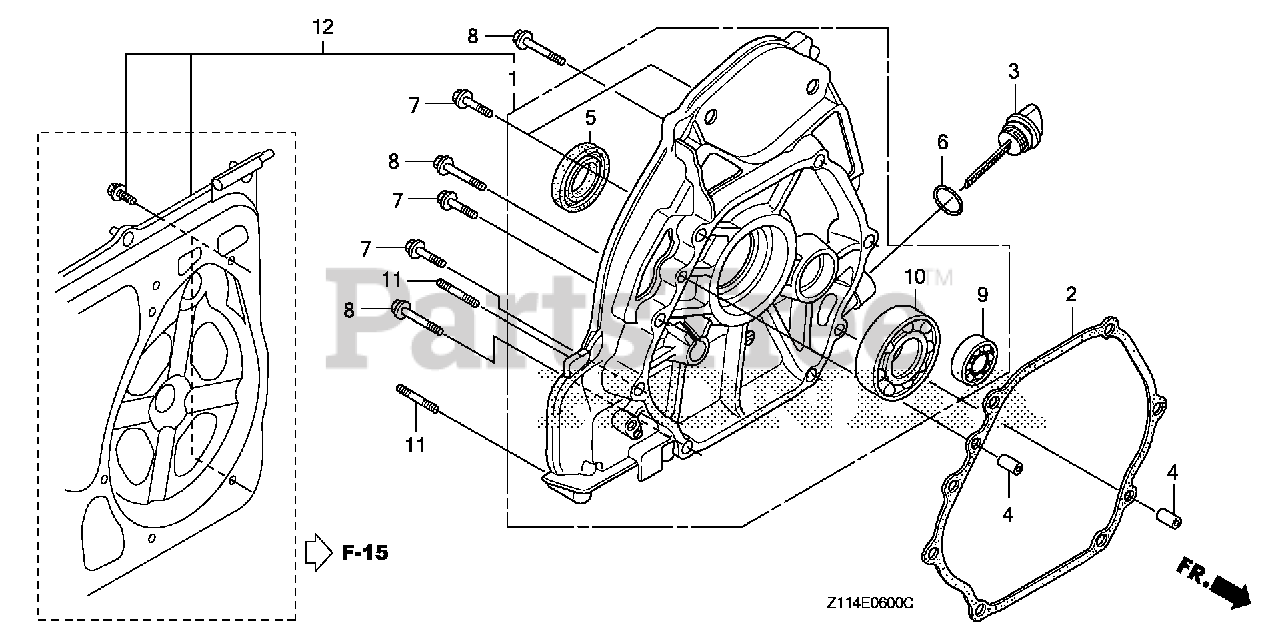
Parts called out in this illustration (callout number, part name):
1	COVER KIT, CRANKCASE
1	COVER ASSY., CRANKCASE
2	GASKET, CASE COVER
3	CAP, OIL FILLER
4	PIN, DOWEL (8X12)
5	OIL SEAL (35X52X8)
6	O-RING (26X2.7)
7	BOLT, FLANGE (8X40) Use up to Engine SN 1003236.
8	BOLT, FLANGE (8X60)
9	BEARING, RADIAL BALL (6202)
10	BEARING, RADIAL BALL (6207)
11	BOLT, STUD (8X55)
12	COVER KIT, CRANKCASE
